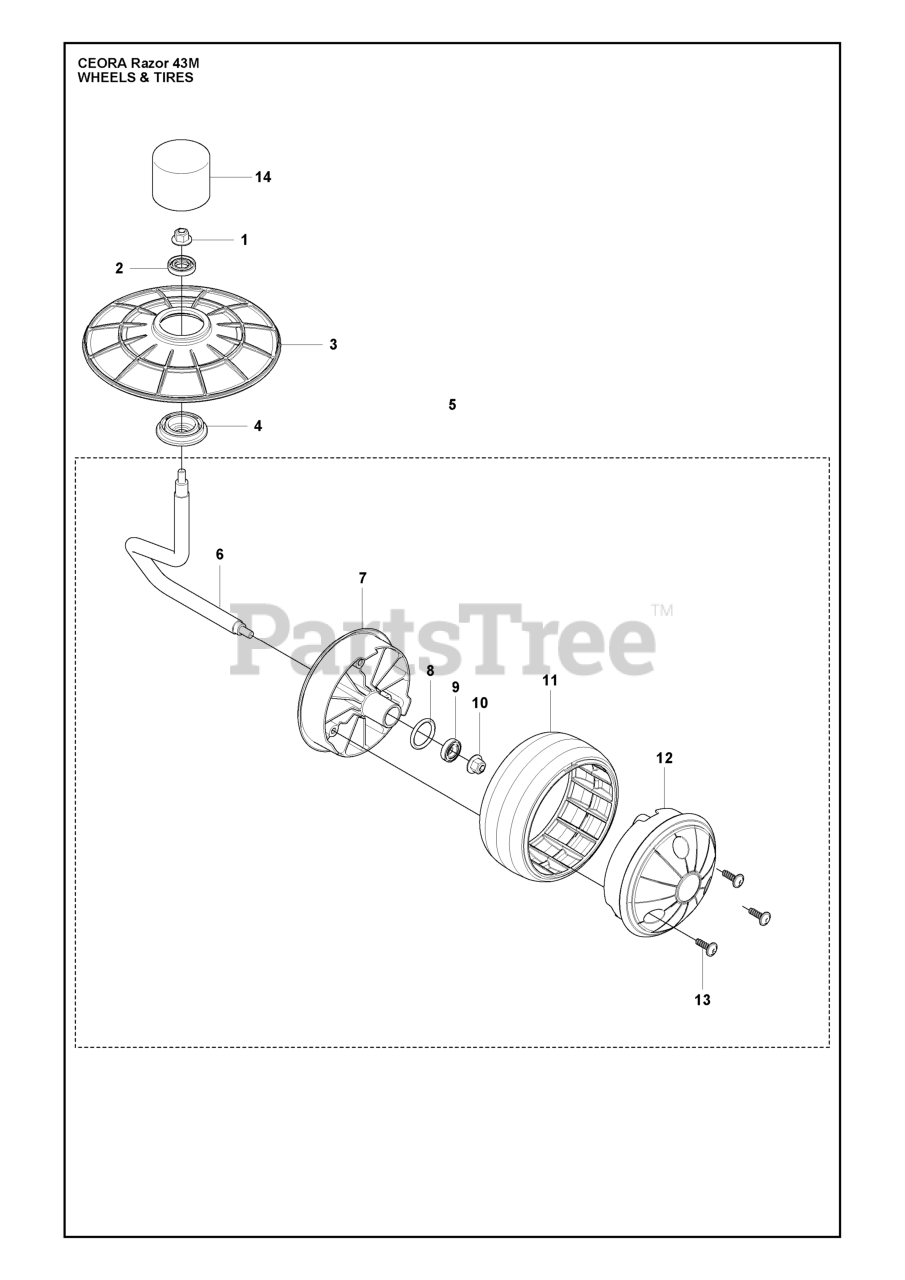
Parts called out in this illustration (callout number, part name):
1	NUT FLANGE
3	BELLOWS FRONT WHEEL
5	WHEEL ASSY CUTTING DECK
6	SPINDLE FRONT WHEEL
7	WHEEL ASSY
8	O-RING
9	BEARING BALL
10	NUT FLANGE
11	WHEEL RUBBER TYRE
12	WHEEL FRONT WHEEL OUTSIDE
13	SCREW ITXPANT
14	CAP FRONT WHEEL
